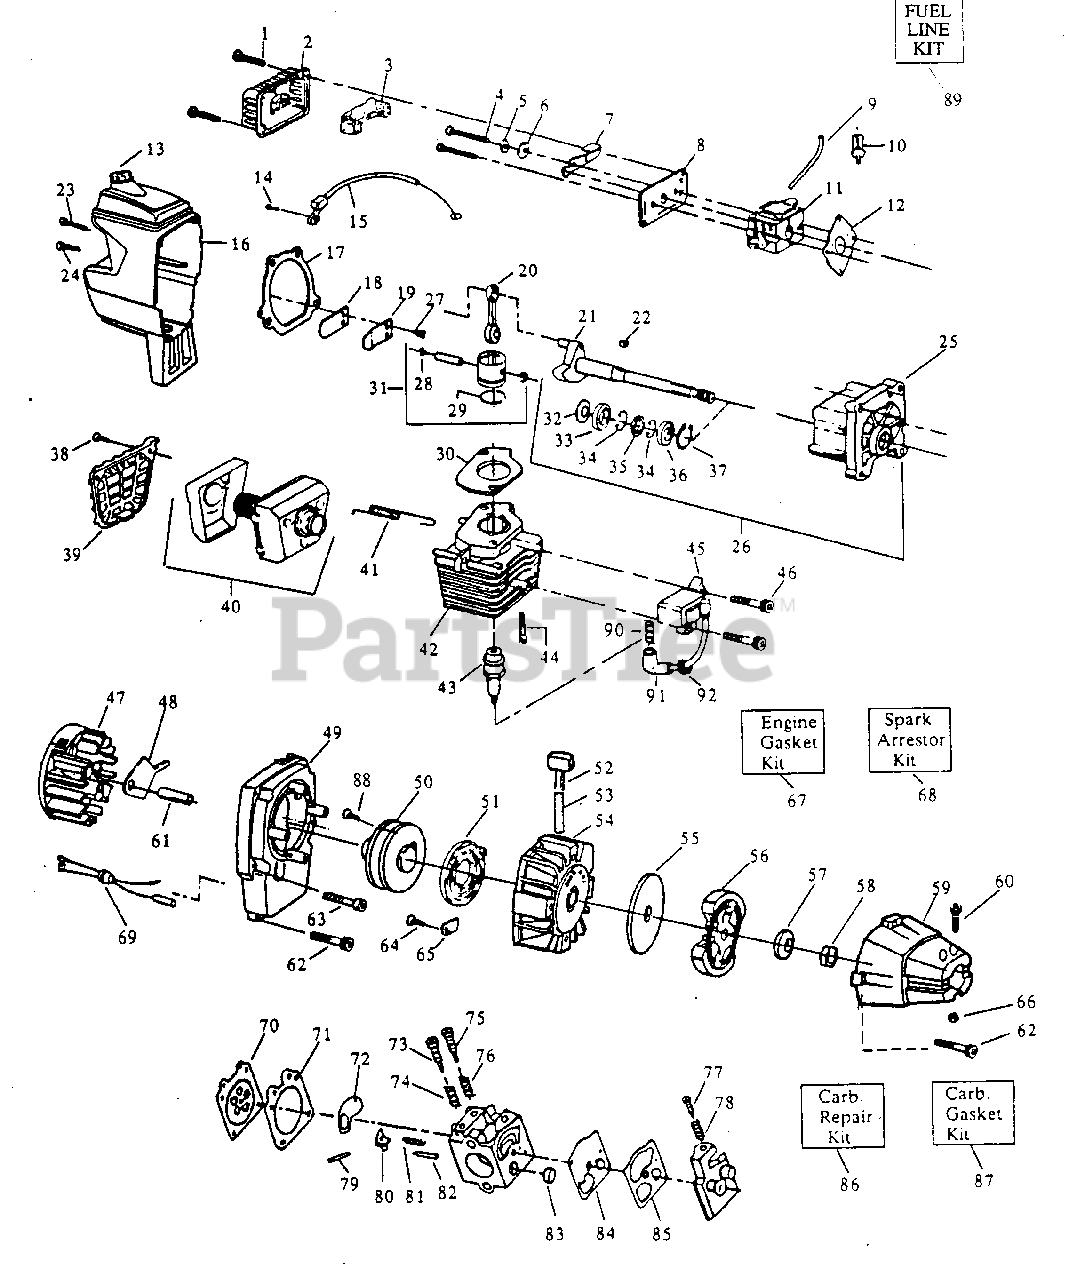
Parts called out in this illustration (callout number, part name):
2	Air Filter Cover
3	Air Filter
4	Screw
5	Spacer
6	Wave Washer
7	Choke Shutter
8	Air Filter Plate
9	Fuel Line
10	Fuel Pick-Up Assy.
11	Carburetor (WA-199)
12	Carburetor Gasket
13	Fuel Cap Assy.
15	Throttle Cable Assy.
16	Shroud & Tank Assy.
19	Reed Stop
20	Connecting Rod Assy.
21	Crankshaft Assy.
22	Flywheel Key
25	Crankcase Assy. (Inc.33 - 36)
26	Crankcase & Crankshaft Assy.
28	Piston Pin Retainer
29	Piston Ring
30	Cylinder Gasket
31	Piston Kit (Inc.34, 35 & Pin)
33	Inner Bearing
34	Retaining Ring
35	Crankshaft Seal
36	Outer Bearing
37	Crankshaft Retaining Ring
39	Muffler Guard
40	Muffler Kit
41	Muffler Spring
42	Cylinder
43	Spark Plug
45	Ignition Module Kit
46	Screw
47	Flywheel Assy.
48	Flywheel Counterweight
49	Fan Housing
50	Starter Pulley Kit
51	Starter Spring
52	Starter Handle
53	Rope Kit
54	Pulley Housing Assy.
55	Clutch Washer
56	Clutch Assy. Kit
58	Nut
59	Clutch Housing
65	Pulley Retainer
67	Engine Gasket Kit
68	Spark Arrestor Kit
69	Lead Wire/Grommet Assy.
70	Metering Diaphragm
71	Metering Diaphragm Gasket
72	Circuit Plate Gasket
73	Hi Speed Needle
74	Hi Speed Needle Spring
75	Idle Needle
76	Idle Needle Spring
77	Idle Speed Screw
78	Idle Speed Spring
79	Metering Pin
80	Metering Lever
81	Metering Lever Spring
82	Indlet Needle Valve
83	Inlet Screen
84	Pump Diaphragm
85	Pump Gasket
86	Carb. Kwik Repair Kit
87	Carb. Gasket/Diaphragm
88	Screw with Washer
89	Fuel Line Kit
90	Connector Spark Plug
91	Boot Spark Plug
92	Grommet Plug Wire
